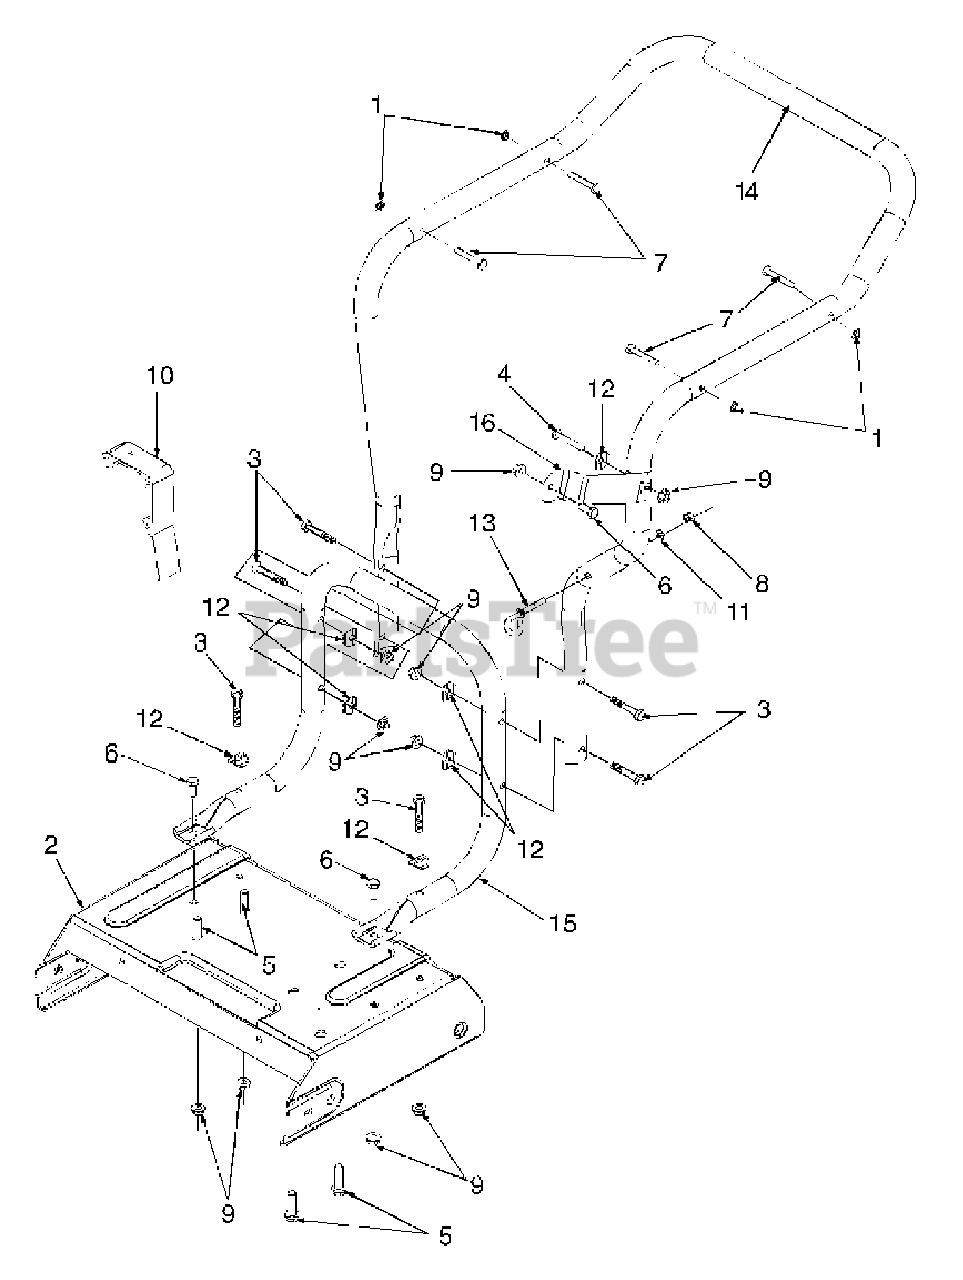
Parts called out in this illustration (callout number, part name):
1	PUSH NUT .250
4	HEX HEAD CAP SCREW 5/16-18 x 1.50
5	HEX LOCK WASH HD - TAP SCREW 3/8-16 x 1.25
6	HEX HEAD CAP SCREW 5/16-18 x .75
7	PIN: STUD .250 x 1.75
8	HEX NUT 1/4-28
9	HEX FLANGE LOCK NUT 5/16-18
10	MOUNTING ADAPTER
11	LOCK WASHER 1/4
12	SADDLE WASHER .320 ID x .83 OD
13	EYE BOLT
